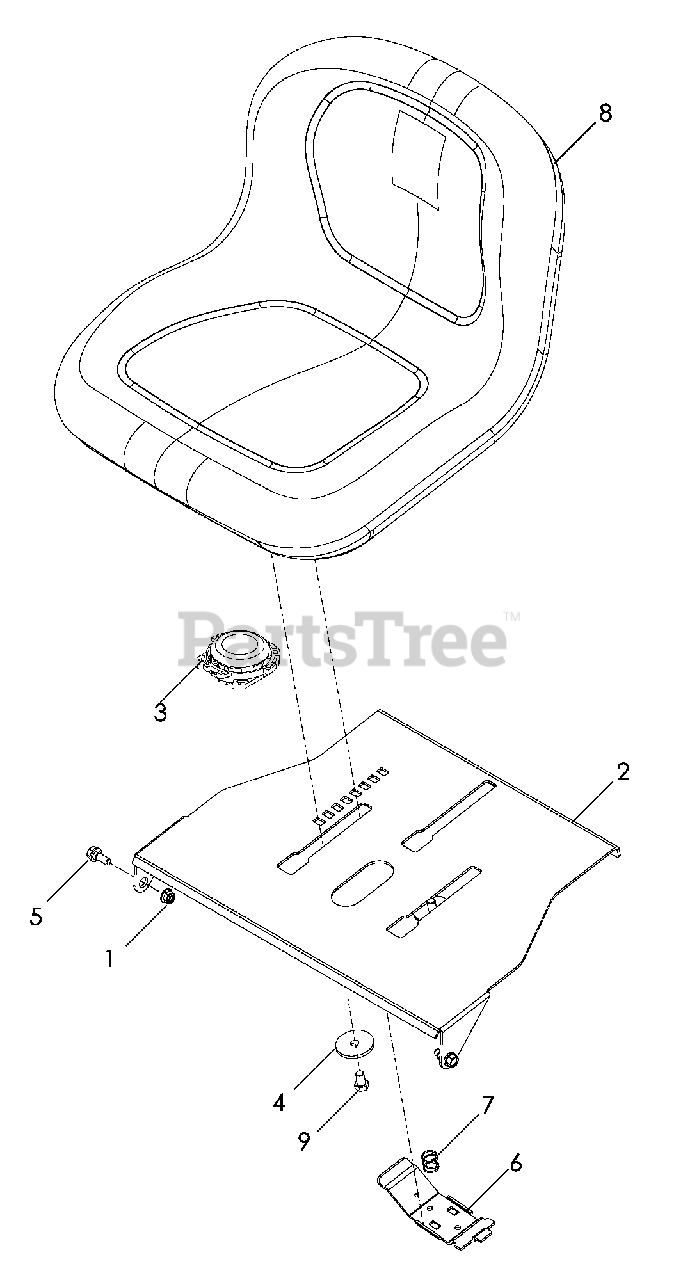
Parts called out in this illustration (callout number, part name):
1	NUT 5/16-18 FLANGE NYLOC
2	PLATE, SEAT
3	SWITCH, SEAT N/C
4	WASHER 3/8 SPECIAL
5	BOLT 5/16-SHOULDER
6	HANDLE, SEAT SLIDE
7	SPRING, SEAT SLIDE
8	SEAT
9	HCS 3/8-16 x 5/8
